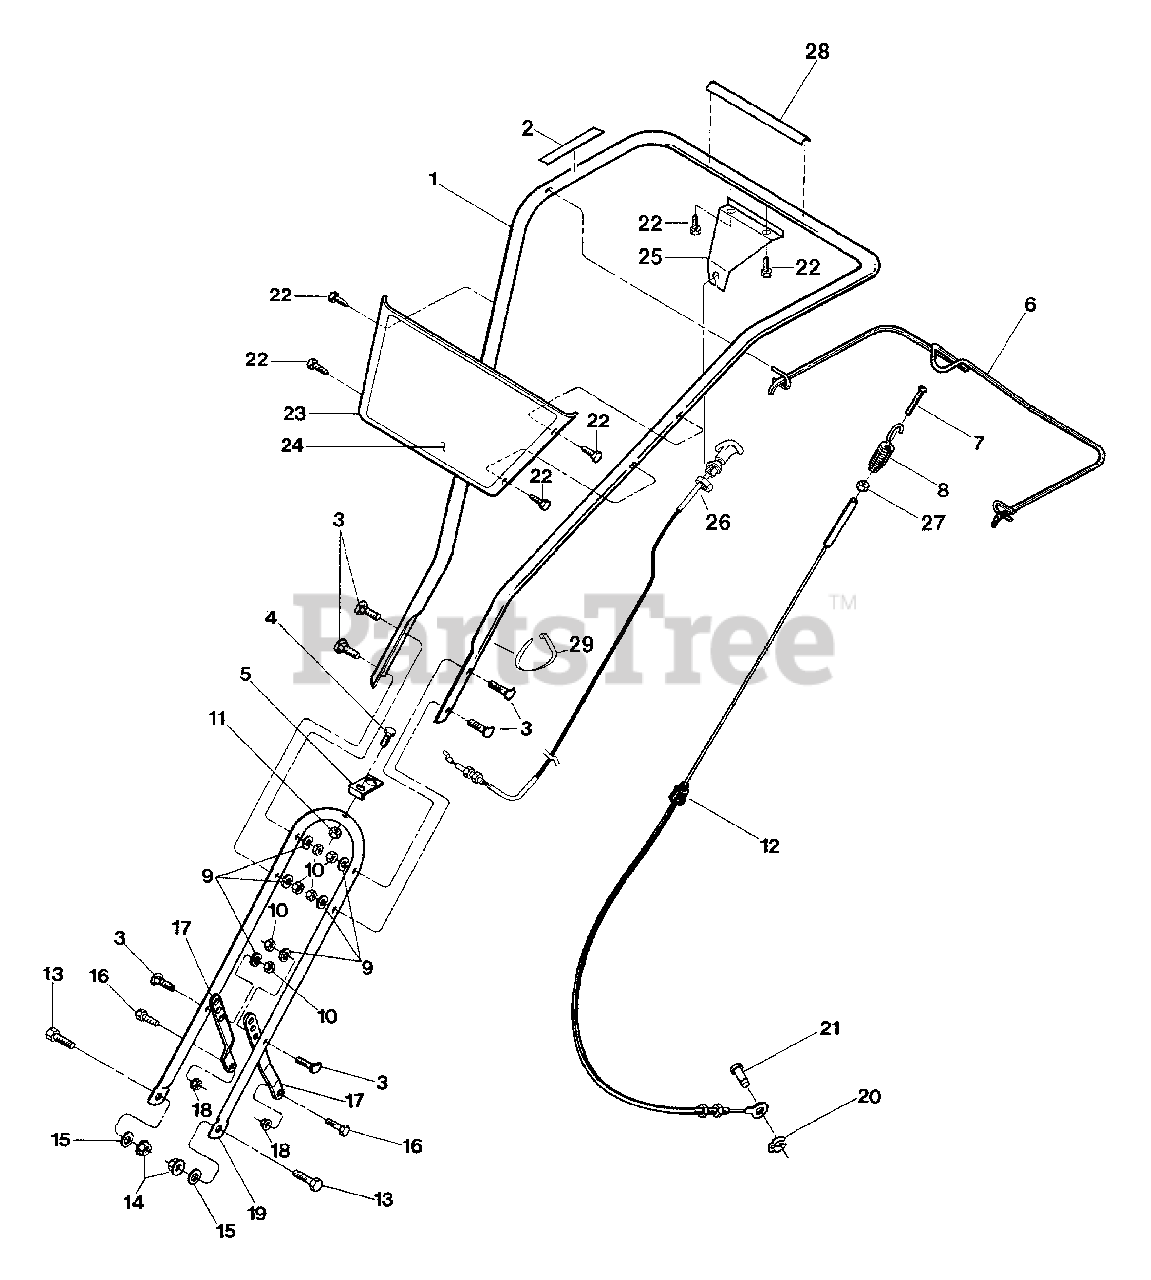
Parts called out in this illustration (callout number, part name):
1	Upper Handlebar
2	Decal, Forward Clutch Bail
3	Hex Hd. Screw. 5/16-18 x 1-1/2
4	Hex Screw, 1/4-20 x 1-1/4
5	Bracket, Forward Clutch Cable
6	Bail, Forward Clutch
7	Screw, #10-24 x 2
8	Spring, Forward Clutch
9	Lockwasher, 5/16
10	Hex Locknut, 5/16-18
11	Hex Locknut, 1/4-20
12	Cable Assy, Forward Clutch
13	Hex Screw, 3/8-16 x 3/4
14	Hex Locknut, 3/8-16
15	Flat Washer, 3/8
16	Hex Screw, 5/16-18 x 3/4
17	Handlebar Support
18	Hex Locknut, 5/16-18
19	Lower Handlebar
20	Klip Ring
21	Clevis Pin
22	Hex Screw, 1/4-20 x 1/2, Self-Tap
24	Decal, Model Name/Logo
25	Bracket, Reverse Clutch Cable
26	Cable Assy, Reverse Clutch
27	Hex Nut, #10-24
28	Decal. Reverse Drive Control
29	Cable Tie
